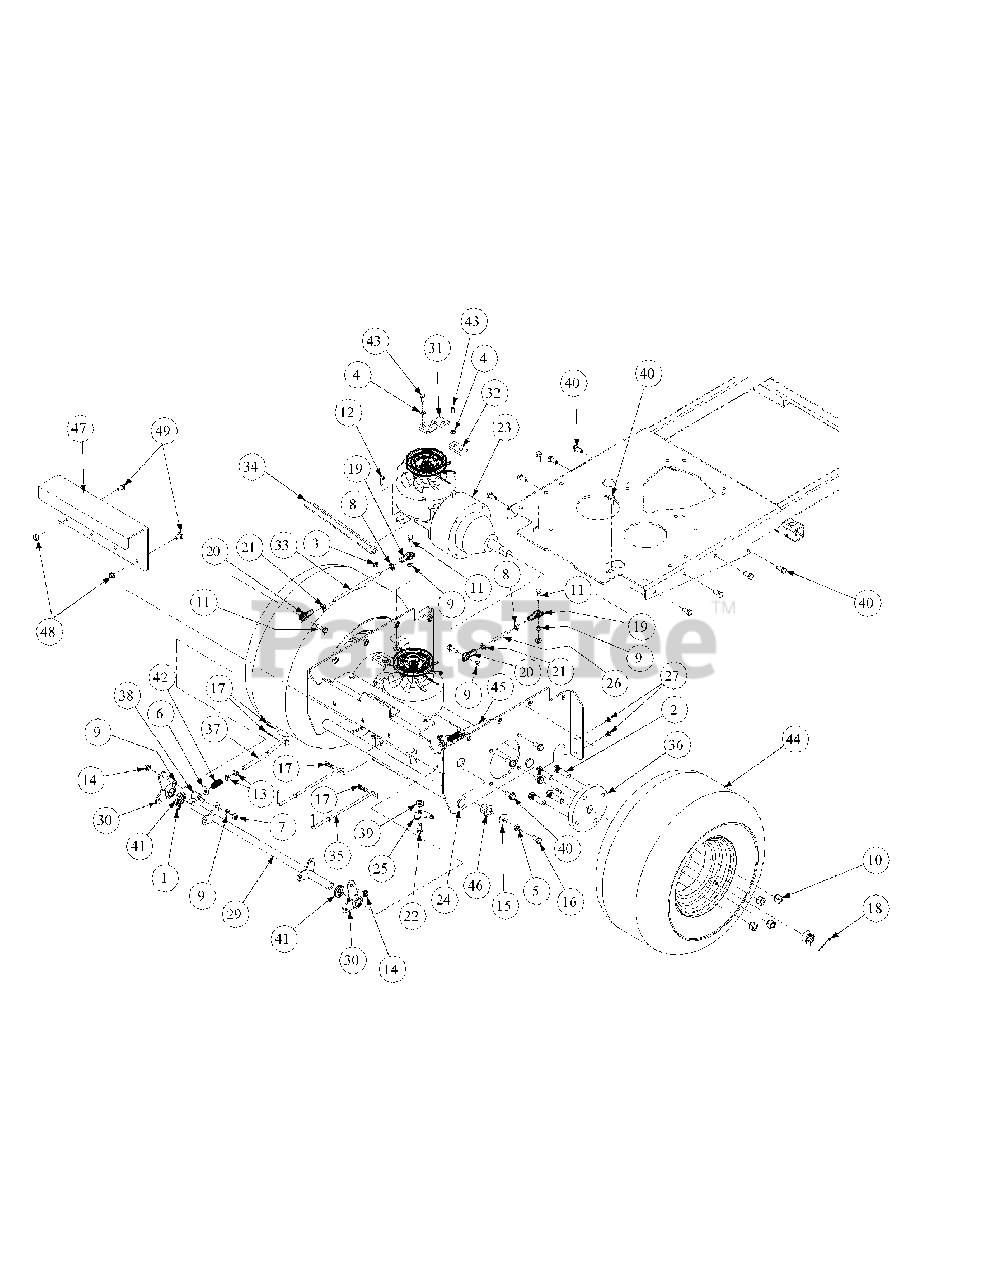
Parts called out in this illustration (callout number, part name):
1	Nut, 3/8-24, Jam
2	Wheel Bolt, 1/2-20 x 1-3/8
3	Nut, 1/4-20, Nylon Insert
4	Washer, 1/4 Zinc
5	Lock Washer, 3/8 Zinc
6	Washer, 3/8 Zinc
7	Nut, 5/16-18, Nylock
8	Nut, 5/16-24, Hex
9	Washer, 5/16 Zinc
10	Lug Nut, 1/2-20
11	Hex Head Cap Screw, 5/16-18 x 1.0
12	Hex Head Cap Screw, 1/4-20 x .75
13	Nut, 3/8-24, Hex Jam
14	Nut, 5/16-18, Hex Flange Lock
15	Washer, 1.25 x .411 x .100
16	Hex Head Cap Screw, 3/8-16 x .75
17	Cotter Pin, .072 x 1.12 Long
18	Cotter Pin, .125 x 1.5 Long
19	Right Hand Rod End, 5/16
20	Left Hand Rod End, 5/16
21	Nut, 5/16-24, Hex
22	Screw, 5/16-18 x 0.750
23	Transmission, Eaton
24	Transmission Weldment
26	Control Rod
27	Rivet, 1/4 x 5/8
28	V-Belt
29	Pivot Rod Weldment
30	Bellcrank Assembly
30	Grease Fitting
31	Transmission Control Lever
32	Brake Control Lever
33	Lower Control Rod
34	Transmission Bracket
35	Transmission Rod
36	Wheel Motor Hub
37	Brake Rod
38	Pivot Brake Joint
39	Lever Spacer
40	Screw, 3/8-16 x .875
41	Collar, .750 ID x 1.25 OD x .37
42	Spacer, .625 OD x .390 ID x 1.2
43	Hex Head Cap Screw, 1/4-28 x 5/8
44	Wheel Assembly, 18.00 x 8.50-8
45	Lower Brake Rod
46	Hex Flange Bearing, .752 ID
47	Rear Guard
48	Hex Flange Lock Nut, 3/8-16
49	Carriage Bolt, 3/8-16 x .75
